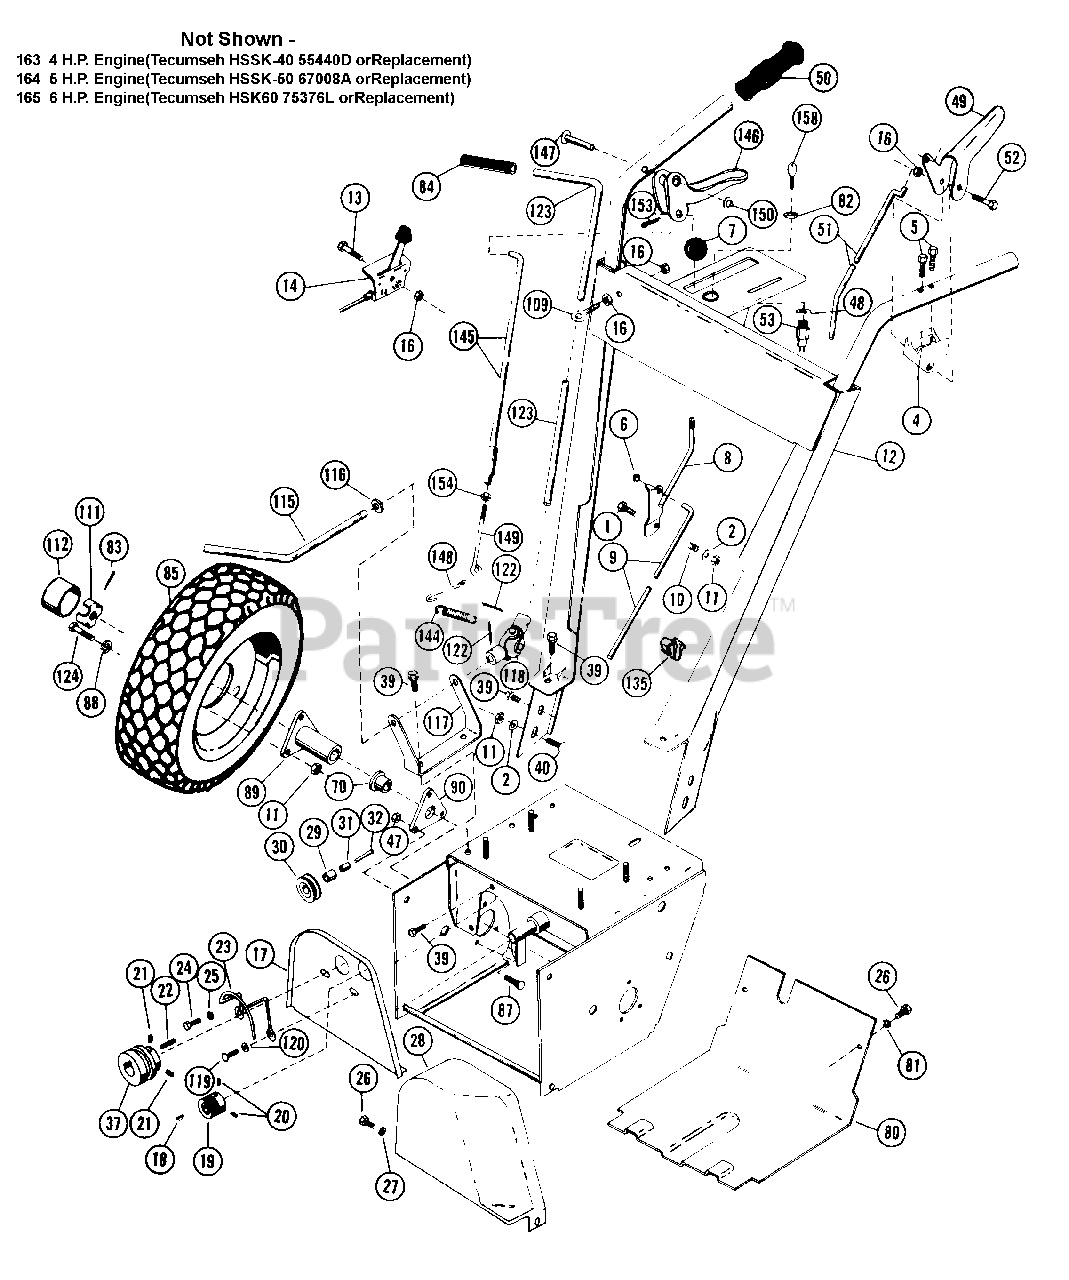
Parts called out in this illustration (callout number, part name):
1	BLT-HEX .31-18X1.50 PL GR2
2	WSHR-FL-STL.312X.734X.065PL
4	HANDLE PIVOT
5	SCR-TAP 12-14X1.50 CROVH PL BT
6	SPRINGGRIP FASTENER
7	SHIFT BALL
8	SHIFT HANDLE
9	SHIFT ROD
10	SG-COMP .105X.585X.75
11	NUT-LK .312-18 GR A PL
12	HANDLEBAR ASSEMBLY
13	BLT-HEX .25-20X.75 PL GR2
14	THROTTLE CONTROL
16	NUT-LK-CTR .250-20 PL
17	INNER BELT COVER
18	KEY-WDRF .125X.625X.250 SAE5
19	CAMSHAFT SHEAVE
20	SCR-SET .25-20X.25 SKHCUPNY OH
21	SCR-SET .32-18X.38 SKHCUPNL OH
22	KEY-SQ .188X1.0X.188 SAE 8630
23	BELT FINGER
24	BLT-HEX .31-24X.75 PL GR5
25	WSHR-LK .312X.097 PL HVY
26	BLT-HEX .25-20X.50 PL GR2
27	WSHR-FL-STL .250X.562X.049 PL
28	OUTER BELT COVER
29	BSHG-SLV .500X.625X.937
31	IDLER SHAFT
32	RVT-TBLR .187X1.218 OH ST PL
33	WSHR-FL-STL .38X.875X.083 PL
34	PIN-HAIR INT .08X.18X1.18
35	PIN-COTR .09X.75 PL
36	IDLER ARM ASSEMBLY
37	ENGINE SHEAVE
38	CAP, .50 ROD YWZC
39	BLT-SERHFWH .31-18X.50 PL
40	BLT-RDHDSQSHNK .31-18X.50 YZ
41	BLT-HEX .25-20X.38 PL GR2
42	WSHR-LK-EXT. 250 ID
43	NUT-LK-CTR .50-20 PL
44	FRICTION DISC
45	FRICTION DISC HUB
47	NUT-LK-FLG .250-20 PL
48	WSHR-LK-INT .625X.045 PL
49	CLUTCH HANDLE ASSEMBLY
50	GRIP
51	CLUTCH ROD
52	BLT-HEX .25-20X1.75 PL GR2
53	KEY SWITCH
54	ROD ADAPTER
56	BSHG-SLV .334 X .502 X 1.437
57	SHIFT LEVER
58	BLT-HEX .31-18X.75 PL GR2
59	BLT-RDHDSQNK .31-18X2.0 SHT PL
60	SHIFT LINK
61	WSHR-FL-STL .505X1.000X.062
62	BEARING RETAINER
63	BRG-BALL .500X1.38X.437
64	CARRIER
65	PIN-ROLL .188X1.00
66	RVT-POP .187X.402 DOME ST
67	HEX SHAFT
68	RVT-POP.125 X .294 DOME
69	BEARING RETAINER
70	BSHG-FLG .750X1.000X.625X1.250
71	TRACTOR FRAME
73	KEY-FTHR .188X1.25X.187 SAE
74	KEY-WDRF .25X.750X.313 SAE91
75	AXLE SHAFT
76	PIN-ROLL .125X1.00
77	RETAINER PLATE
79	SPUR GEAR, FELLOWS 35T .750 ID
81	WSHR-LK .250X.077 HVY PL
82	NUT .625-32 ALUM
83	PIN-COTR .12 X 1.25 PL
85	T/WHL ASS,Y
85	TIRE & WHEEL ASSEMBLY
85	TIRE 4.10/3.50-4
85	TUBE
85	T/WHL ASSY 4.80 X 8 AGRI LUG
85	WHL
85	BLT-HEX .38-16X.63 PL GR2
85	WSHR-LK .375X.094 MED PL
85	NUT-HEX .375-16
87	SCR-SLTR-SERNK .25-20X.62 PL
88	WSHR-LK-EXT .500X.040 MED
89	WHEEL HUB
90	SUPPORT, BEARING
91	KEY-WDRF .125X.500X.203 SAE 3
92	SPINDLE
93	DRIVE DISK
94	ROD ADAPTER
96	DRIVE SPINDLE HOUSING
97	DEADMAN LEVER
98	BLT-HEX .25-20X.75 PL GR5
99	DEADMAN BRACKET
100	BEARING SPACER .75 X .5 X.88
101	SPINDLE HOUSING
102	DRIVE SHEAVE
103	V-BELT, SPECIAL-RAW EDGE (SET)
105	BLT-HEX .31-18X1.00 PL GR 2
106	RATCHET PLATE
107	ADJUSTMENT LINK
108	SG-TENS .063X.44X2.81 WLD 18
109	ROD HANGER EYEBOLT
111	SPINDLE CUP
112	HUB CAP
113	SG-TENS .125X.437X5.5 WLD 20
115	CLUTCH LEVER ROD
116	WSHR-FL-STL .382X.812X.023 PL
117	SUPPORT BRACKET
118	UNIVERSAL JOINT ASSEMBLY
119	SCR-MCH .31-24X.75 CRFL
120	WSHR-LK-EXT .313X.025
122	PIN-COTR .12X1.0 PL
123	CLUTCH ROD
124	BLT-HEX .31-18X.75 PL GR2
124	BLT-HEX .75-16X2.50 PL GR5
127	CLEVIS PIN
129	WSHR-FL-STL .250X.562X.125 PL
130	WSHR-FL-STL.344X.688X.065PL
131	WSHR-FL-STL.406X.812X.065PL
132	WIRE GROUND
134	SHORTING WIRE
135	CLIP WIRING
136	ENG BOLT SPCR
137	BRACKET SWITCH
138	ACTUATOR SWITCH
139	RETAINER ROD
140	WIRING HARNESS
141	MODULE T SERVICE ASSEMBLY
142	SNAP BUSHING-.437
143	SG-TENS .026X.38X3.75 WLD 1.58
144	SG-TENS .063X.44X1.56
145	ROD UPPER INTERLOCK
146	HANDLE INTERLOCK
147	PIN PIVOT
148	CONNECTING LINK
149	LOWER ROD INTERLOCK
150	PUSH NUT, .25
153	PIN-COTR .06X.50
154	NUT-HEX .250-20 PL
156	SWITCH BOOT
157	SCR-TAP 10-24X.375 HWH PL TR
158	KEYS
159	NUT-LK TOP 10-24 PL
160	BLT-HEX 10-24X.38 PL GR2
161	CONNECTOR
162	STRAP - SWITCH BRACKET
163	4 H.P. Engine(Tecumseh HSSK-40 5544OD orReplacement)
164	5 H.P. Engine(Tecumseh HSSK-50 67008A orReplacement)
165	6 H.P. Engine(Tecumseh HSK60 75376L orReplacement)
